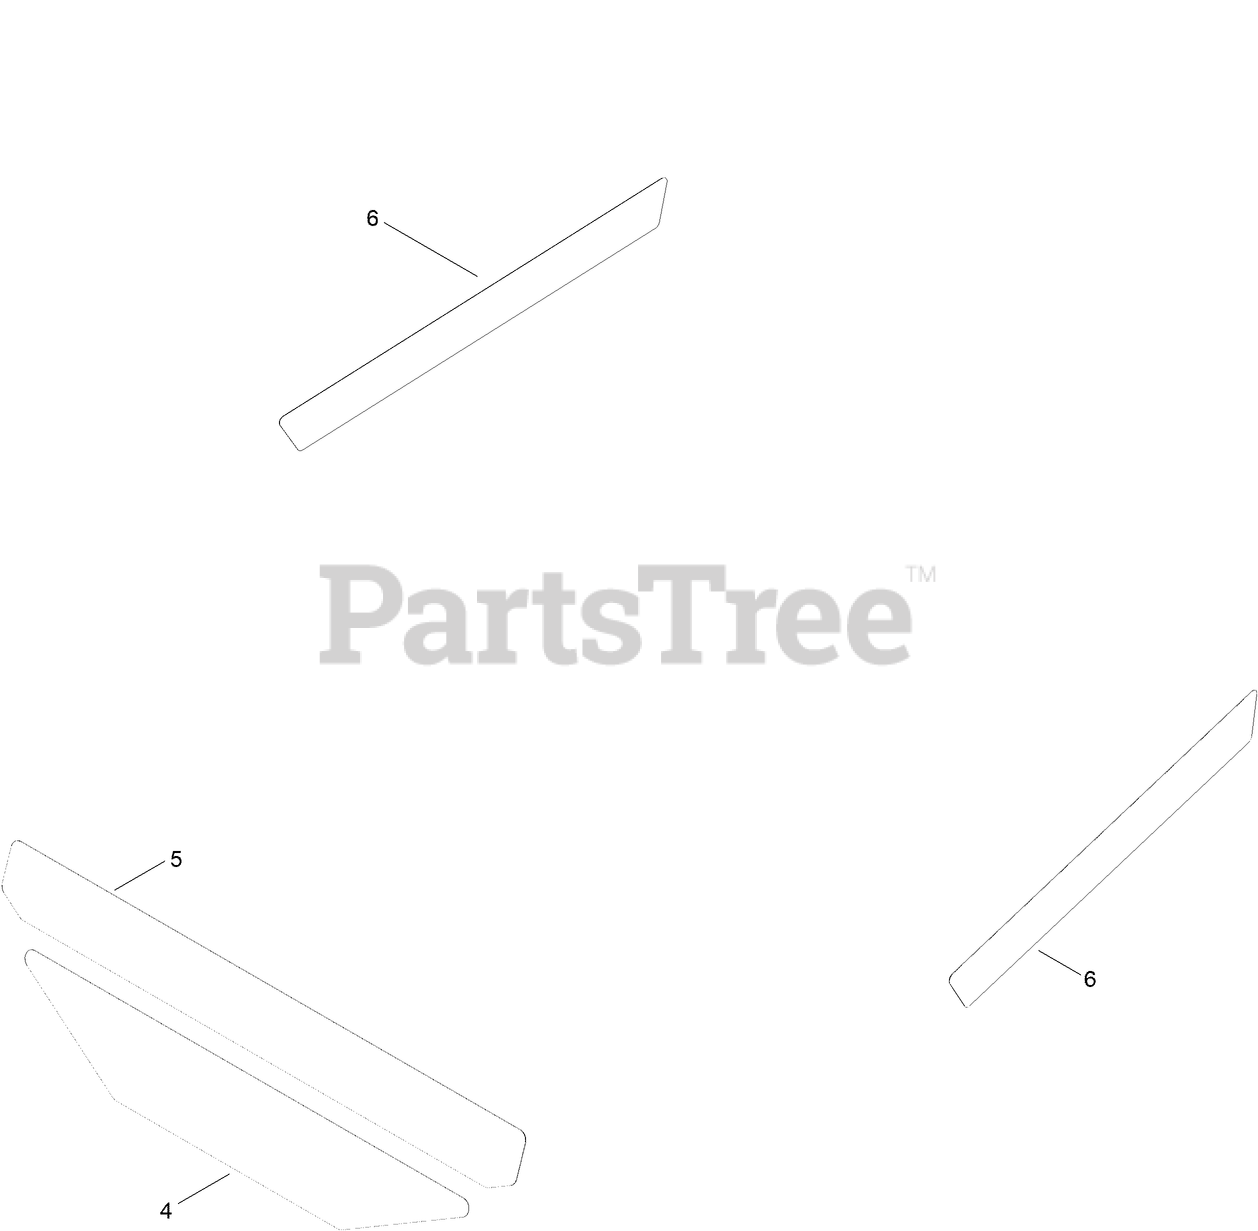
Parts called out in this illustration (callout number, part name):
4	DECAL MX5400T
5	DECAL-TIMECUTTER MAX, SEAT
6	DECAL-TIMECUTTER MAX
